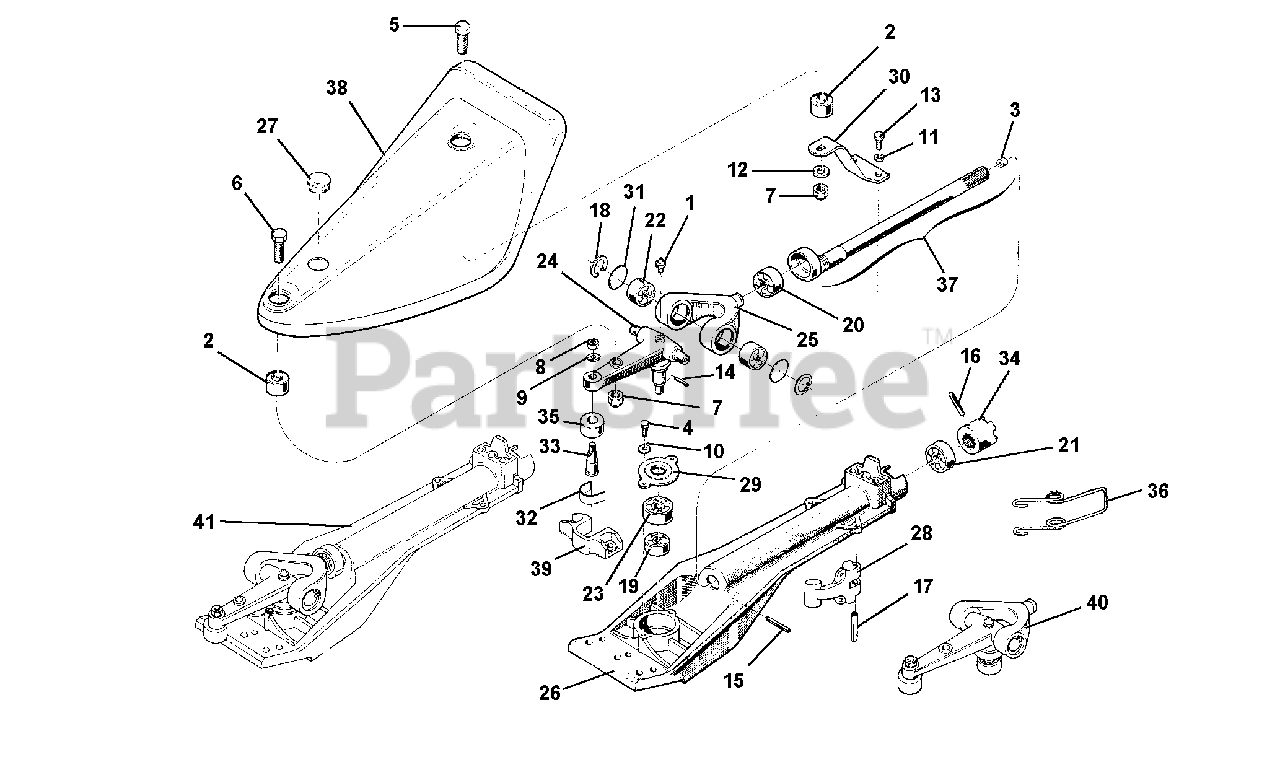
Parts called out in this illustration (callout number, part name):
1	LUBRICATOR M10
4	SCREW TE M6 X 14
5	SCREW M10 X 45
6	SCREW M10 X 60
7	NUT, SELF LOCKING M10
8	SELF LOCKING NUT
9	SUPER WASHER 10 DIN 6796
10	WASHER, LOCK 6.4
11	WASHER, LOCK 8.4
12	WASHER, LOCK 10.5
13	SCREW M8 X 15
14	PIN, LOCKING 3.5 X 26 DIN 1481
15	PIN, LOCKING 5 X 40
16	PIN, LOCKING 6 X 40
17	SPIRAL PIN 8 X 40
18	INSIDE CIRCLIP
19	BEARING 12 X 37 X 12 6301
20	BRNG SKF 17 X 40 X 12 6203 ST
21	BEARING 20 X 42 X 12 6004 2RS
22	BEARING 6202 Z 15 X 35 X 11
23	BEARING 6204 Z 20 X 47 X 14
24	BLADE CONTROL CRANK
26	CUTTER BAR SUPPORT
27	PLUG FOR D 26 HOLE
29	BEARING COVER
30	ELASTIC CONNECTION
31	CLOSING DISC
34	BAR COUPLING
35	BLADE BUSHING
36	LONG SPRING HOOK
37	SHAFT WITH BUSH
38	OSCILLATING PROTECTION
39	BLADE COUPLING
40	CRANK WITH COVER
41	CUTTER BAR ASSEMBLY 205
